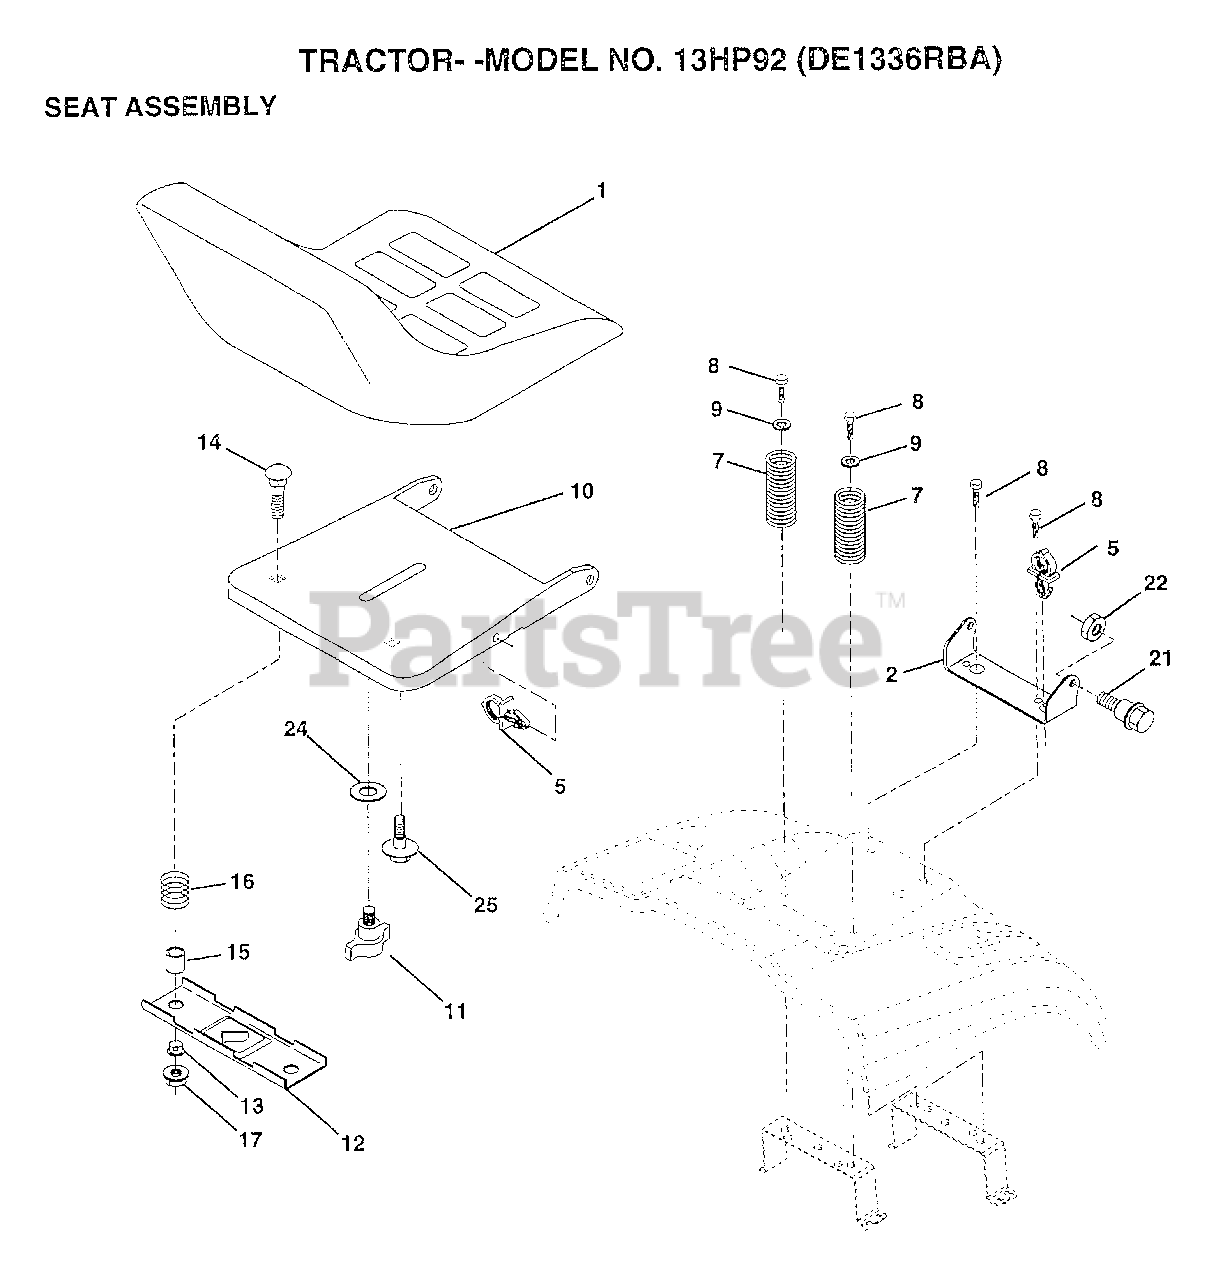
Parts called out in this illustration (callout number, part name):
2	BRACKET PVT SEAT
5	CLIP.PUSH-IN.HING
7	SPRING COMPRESSIO
8	SCREW GTV
9	WASHER
10	PAN-SEAT
12	BRKT SWITCH
13	BUSHING
14	BOLT-RD HD SQ NK
15	SPLIT SPACER
16	SPRING
21	"BOLT,SHOULDER"
22	NUT
23	BOLT
24	WASHER
25	"BOLT,SHOULDER"
26	LOCKWASHER
